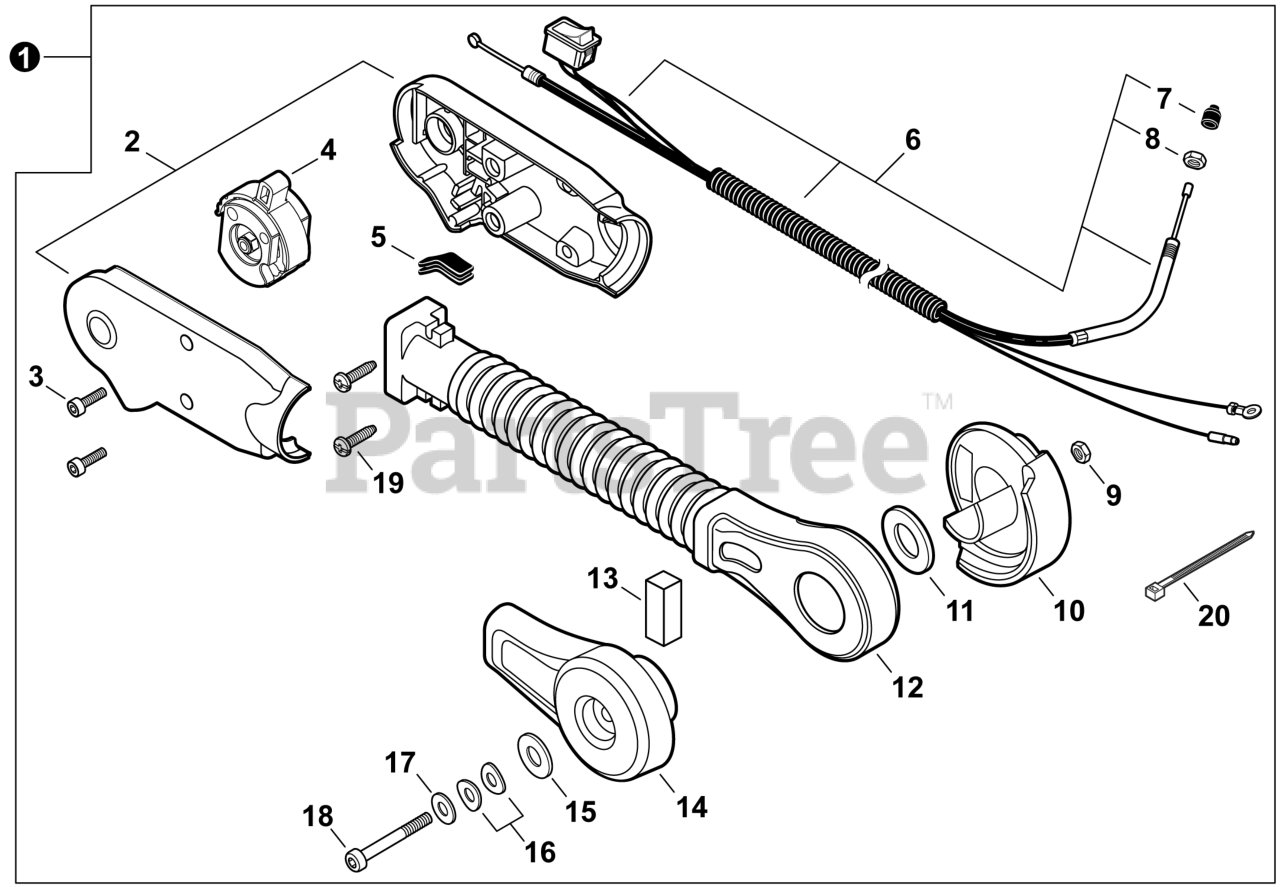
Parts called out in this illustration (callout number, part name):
1	THROTTLE CONTROL KIT - HIP MOUNT
2	GRIP SET, THROTTLE
3	BOLT, TORX 5x16
4	CONTROL, THROTTLE
5	GROMMET
6	CABLE ASSY, CONTROL
7	CAP, DUST
8	NUT, HEX M6
9	NUT, LOCK M6
10	BRACKET, ARM - INNER
11	WASHER 45
12	ARM, THROTTLE CONTROL
13	SEAL, DUST - FOAM
14	BRACKET, ARM - OUTER
15	WASHER 6.6x20x1.6
16	WASHER, FRICTION 6.6x14.3
17	WASHER 6.5x15.5x0.6
18	BOLT, TORX 6x75
20	STRAP, CABLE
